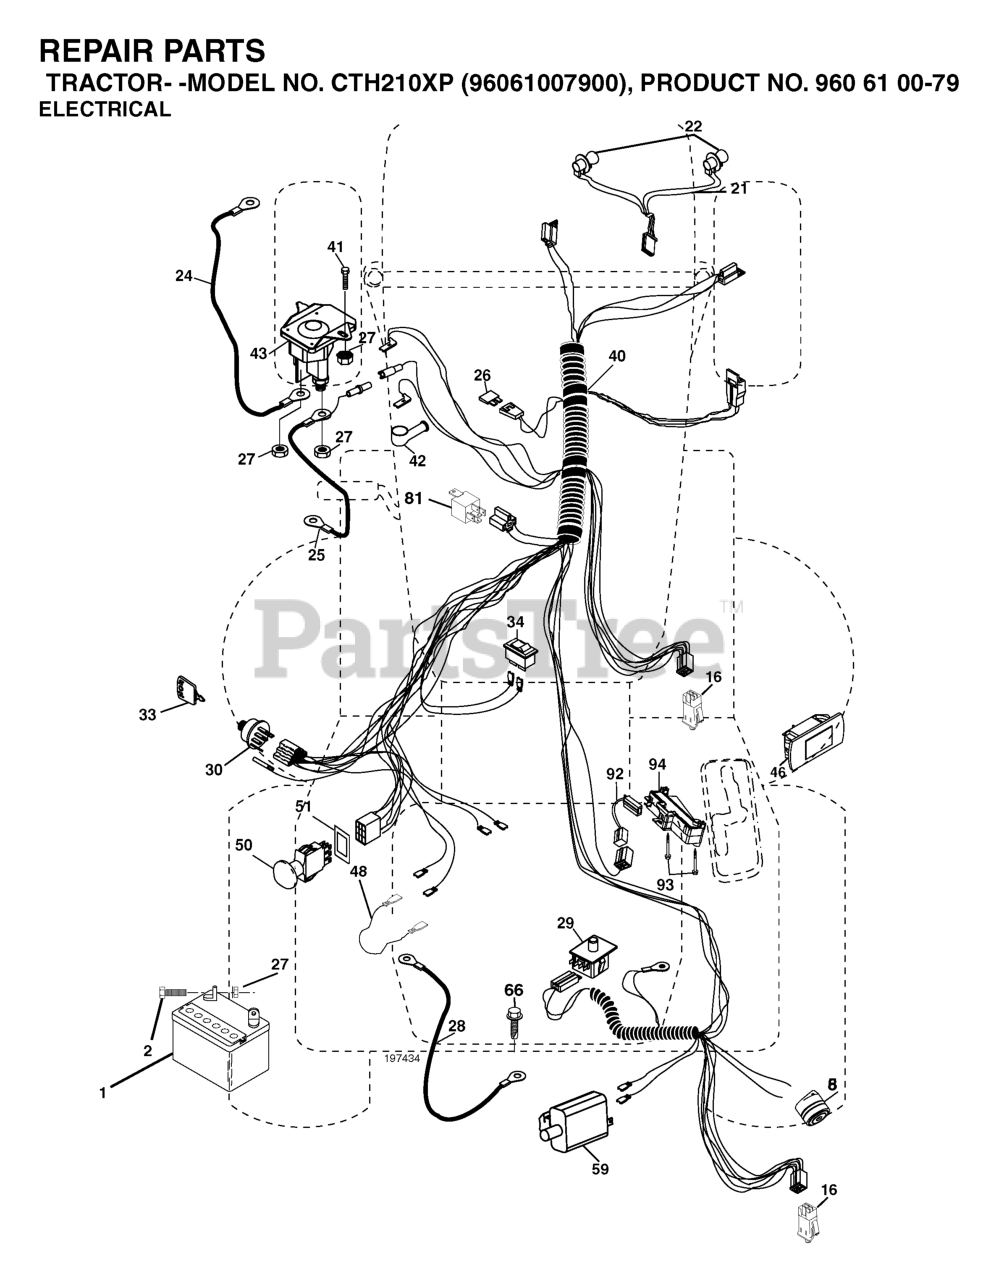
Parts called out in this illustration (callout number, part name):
1	BATTERY 12V .35 AMP
2	BOLT.HEX.1/4.X.3/4.DICHROMATE
16	SWITCH INTERLOOK PUSH-IN
21	HARNESS.W/LIGHT SOCKET
24	BATTERY CABLE GT
25	CABLE BATTERY
26	FUSE 20AMP
27	NUT
28	CABLE GROUND
29	SWITCH.SEAT.DP W/RAMPS
30	SWITCH.IGN.DELTA.W.LGH.ROS
33	KEY MLD GEN DELTA
40	RP HARNESS.IGN.ELECT.REG.CRD
41	BOLT
42	TERMINAL COVER
43	SOLENOID.W/BRASS.PLUNGER
46	GAUGE.SERVICEMINDER.HR
48	ADAPTER.AMMETER
50	RP.PTO.SWITCH.8 TERMINAL.BLACK
51	FRAME RETAINING RING
58	BUZZER
59	.WITCH.FULL BAGGER.INDICATOR
81	RELAY.ASSY.T
92	HARNESS.PIGTAIL.CONSLE
93	SCREW.PLASTITE
94	MODULE.REVERSE.ROS
